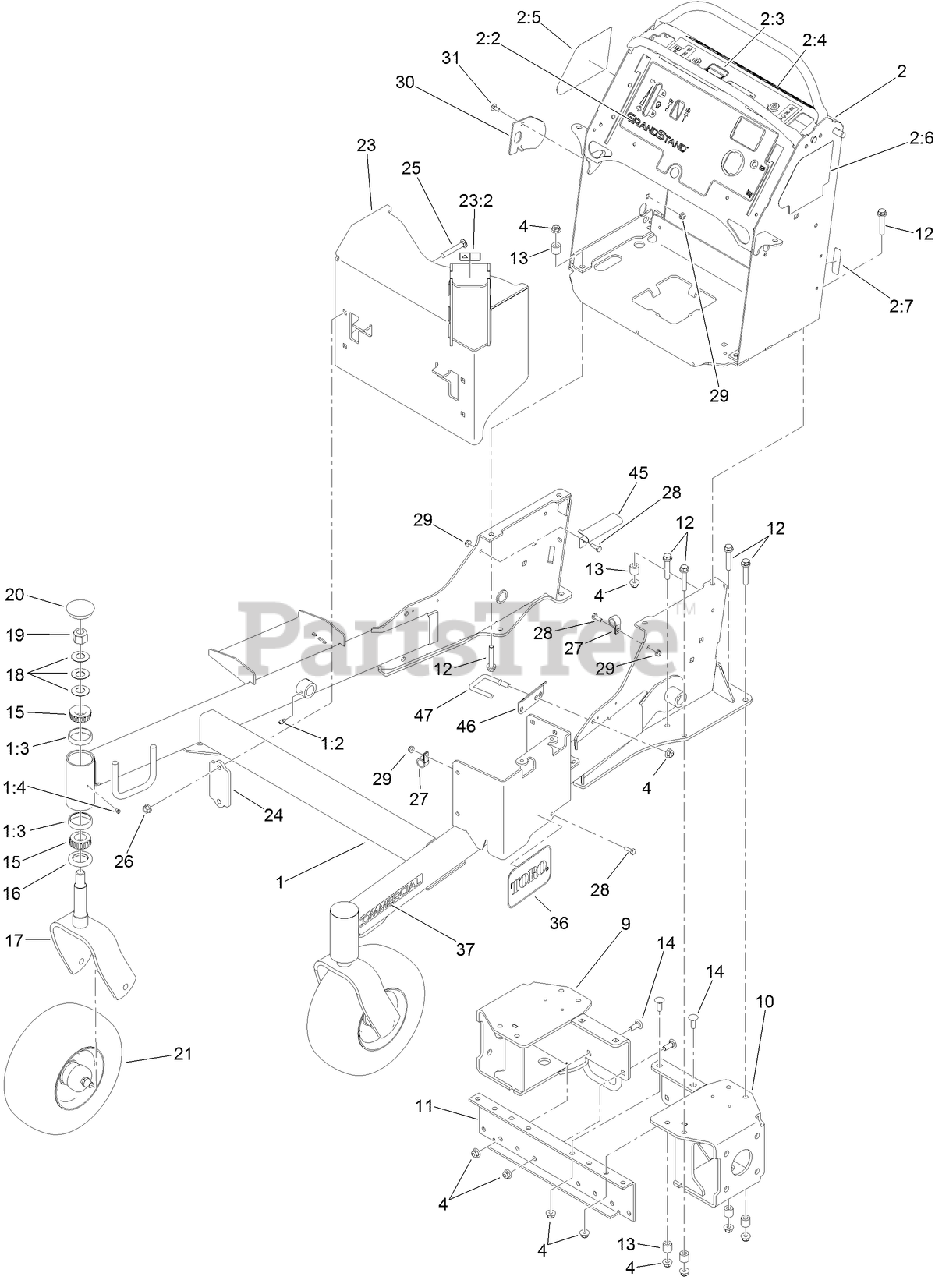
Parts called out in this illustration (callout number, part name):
1	FRONT FRAME ASM
1:2	FITTING-GREASE
1:3	CUP-BEARING
2	CONTROL TOWER ASM
2:2	DECAL-PANEL, CONTROL
2:3	DECAL-OPC
2:4	DECAL-WARNING
2:5	DECAL-HOC
2:6	DECAL-SERVICE/SPARK ARREST
2:7	DECAL-FUSE
4	NUT-HF, NI
9	MOUNT-MOTOR, RH
10	MOUNT-MOTOR, LH
11	MOUNT-MOTOR, CENTER
12	SCREW-HHF
13	SPACER
14	SCREW-CARR
15	BEARING-ROLLER, TAPERED
16	SEAL-GREASE
17	FORK-CASTER
18	WASHER-BELLVILLE
19	NUT-LOCK, NI
20	CAP-GREASE
21	WHEEL/TIRE AND BEARING ASM
23	MUFFLER GUARD ASM
23:2	DECAL-WARNING
24	BRACKET-MOUNTING, GUARD
25	SCREW-CARR
26	NUT-HF
27	CLAMP-CABLE
28	SCREW-HH
29	NUT-HF
30	PLATE-STRIKER
31	SCREW-CARR
36	DECAL
37	DECAL-COMMERCIAL
45	BRACKET-HOSE, FUEL (DOUBLE)
46	GUARD-HOSE
47	GUIDE-HOSE
